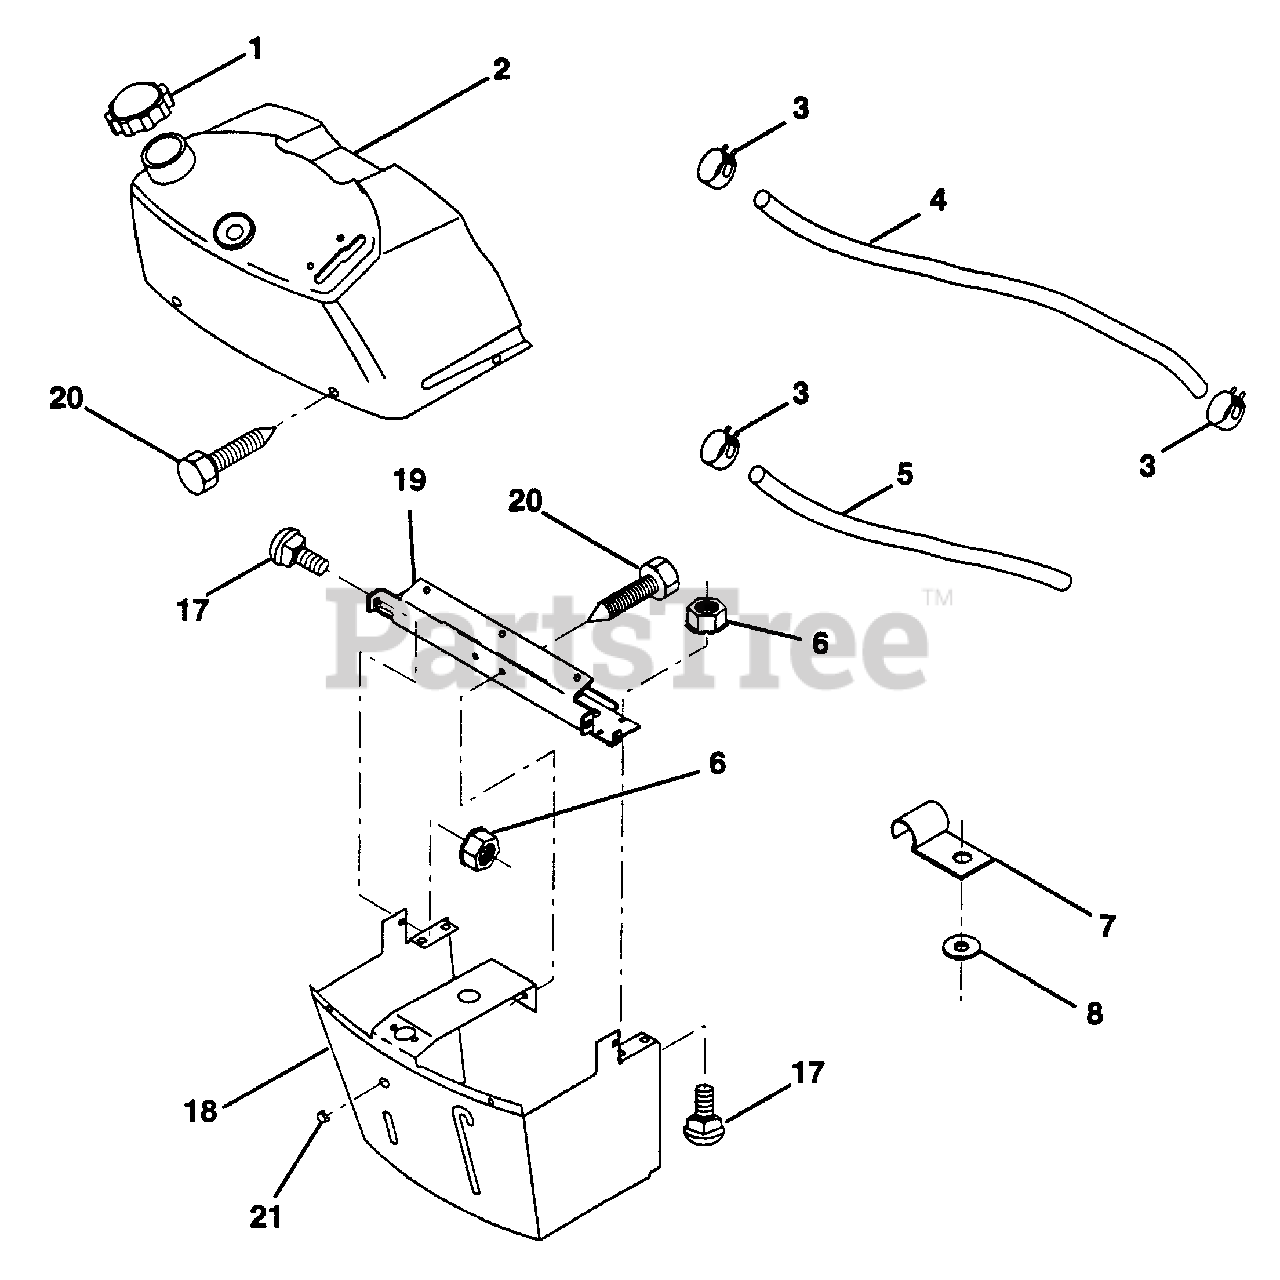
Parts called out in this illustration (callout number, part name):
1	Cap, Fuel Tank
2	Assembly, Dash & Fuel Tank
3	Clamp, Hose
4	Line, Fuel
5	Line, Fuel
6	Nut, Hex, Keps 1/4-20
7	Clip, Fuel Line
8	Washer 9/32 x 3/4 x 16 Gauge
17	Bolt, Carriage 1/4-20 x 1/2 Grade 5
18	Support Assembly, Dash
19	Brace, Cross
20	Screw, Self-Tapping 1/4-20 x 1/2
21	Plug, Dome, Black
